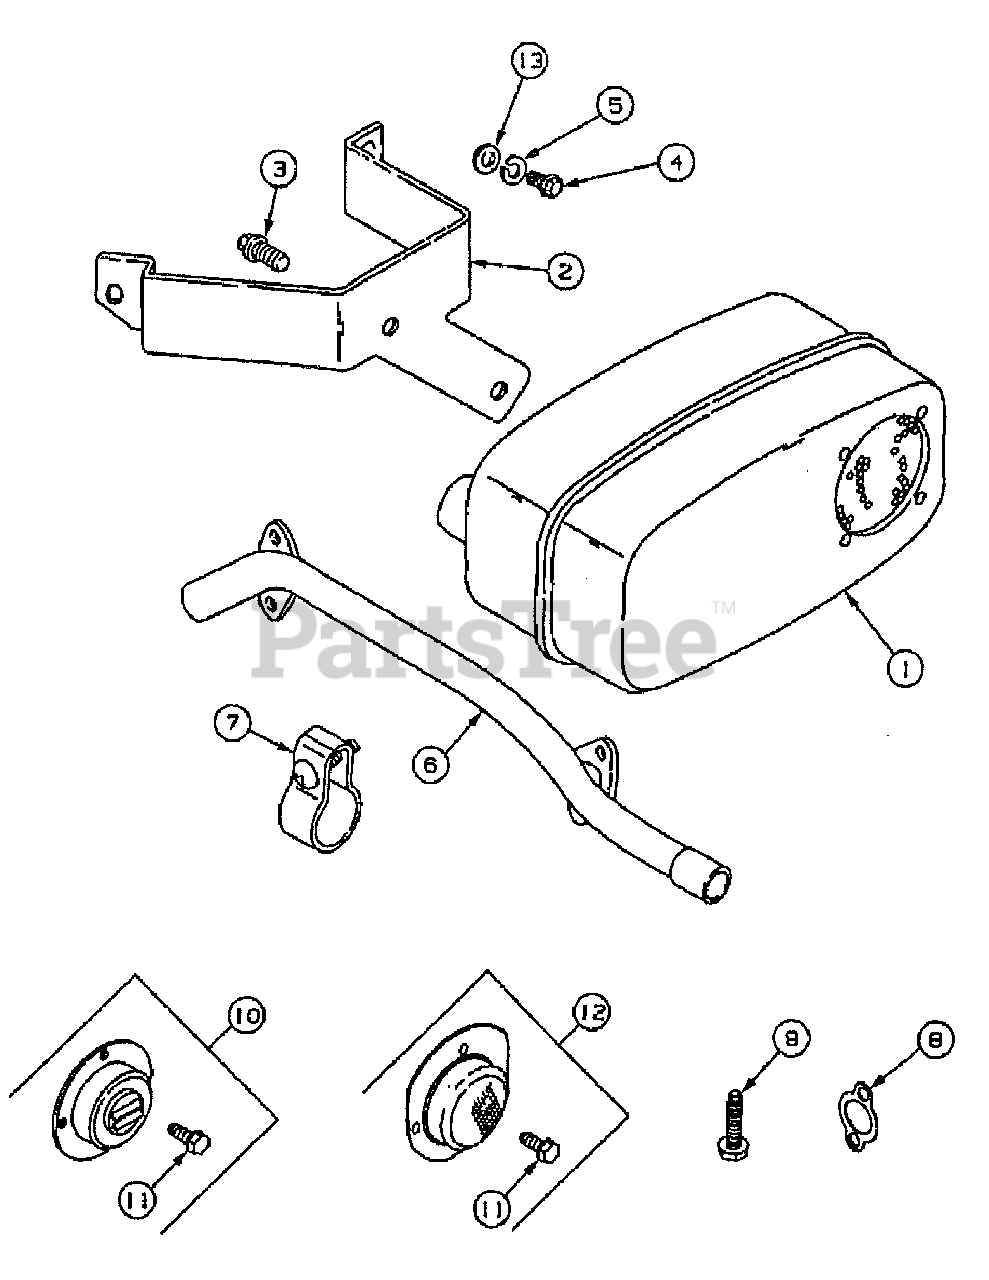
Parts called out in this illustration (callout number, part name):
1	Muffler
2	Bracket, Muffler
3	Screw, Hex Wash Hd Tap, 1/4-20 x .50
4	Screw, Hex Cap, M6-1.0 x 20mm Gr 10.9
5	Washer, Lock 1/4
6	Manifold, Exhaust
7	Camp, Muffler
8	Gasket, Exhaust Manifold
9	Screw, Sem
10	Deflector, Exhaust
11	Screw, Hex Wash Hd Tap, 8-32 x 3/8
12	Arreester, Spark
13	Washer, Flat, .281 x .75 x .105 Thk
